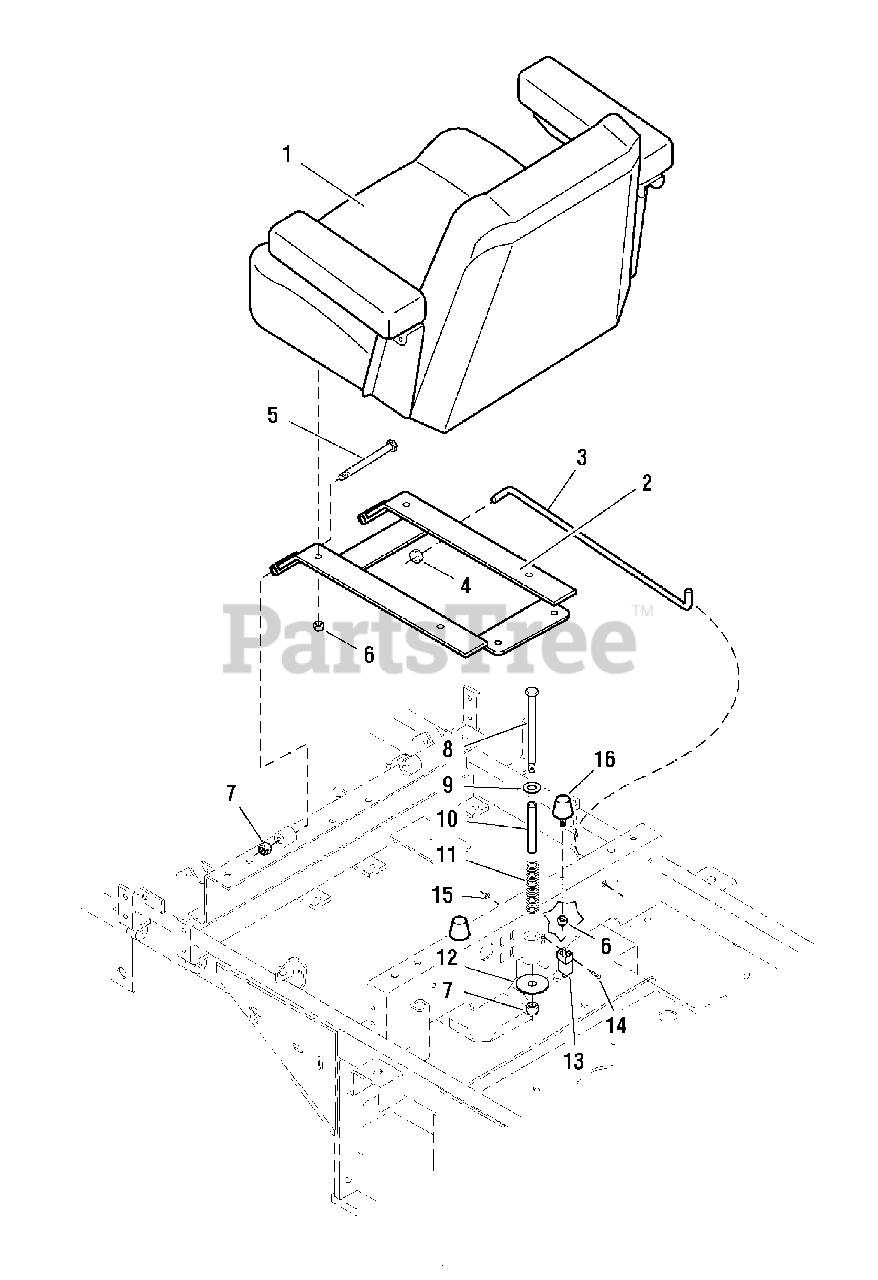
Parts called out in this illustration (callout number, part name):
1	SEAT, Derby
1	SEAT ADJUSTER RAILS
3	SEAT STOP ROD
4	COLLAR, 5/16 Set
5	CAPSCREW, Hex Hd, 3/8-16 x 4
6	NUT, Hex, Nylon Lock, 5/16-18
7	NUT, Hex, Nylon Lock, 3/8-16
8	CAPSCREW, Hex Hd, 3/8-16 x 6
9	WASHER, 3/8
10	SPACER, .38 x .50 x 5.06
11	SPRING, Compression
12	WASHER, 3/8 x 2
13	SWITCH
14	SCREW, #10-24 x 1
15	NUT, Hex, #10-24
16	RUBBER BUMPER
